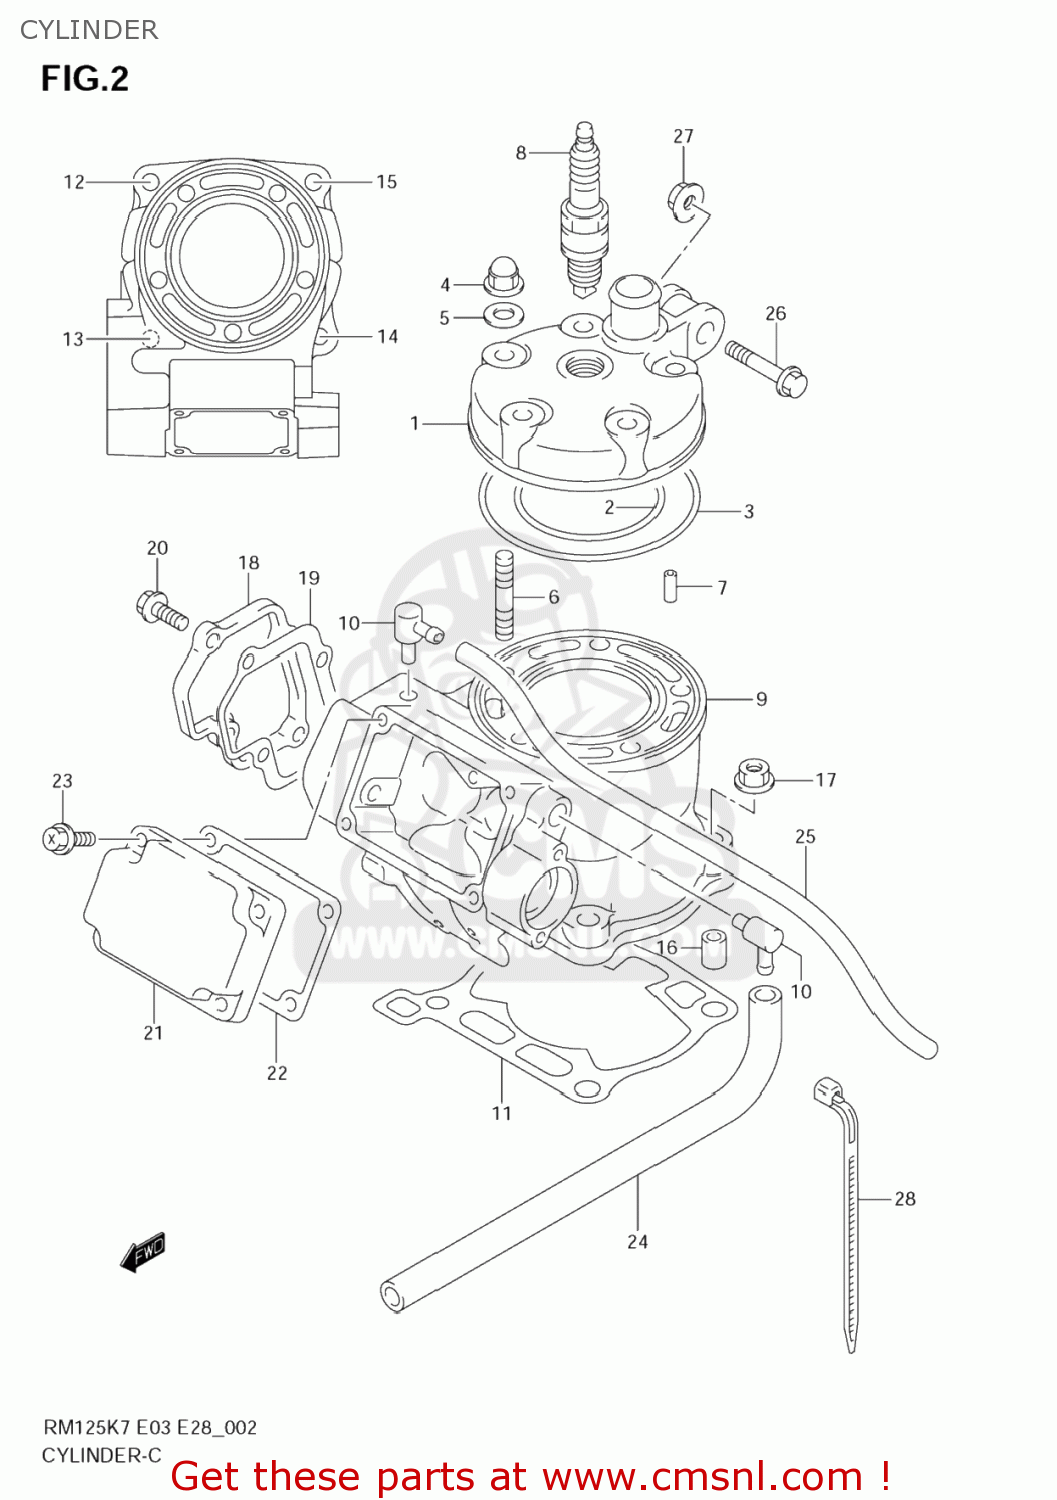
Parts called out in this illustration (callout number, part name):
1	HEAD,CYLINDER
2	O RING,CYLINDER HEAD NO.1
3	O RING,CYLINDER HEAD NO.2
4	NUT
5	GASKET(8.5X17X2.3) (NAS)
6	BOLT,STUD
7	PIN
8	PLUG,SPARK(R6918B-8)
9	CYLINDER SET
10	UNION,BREATHER HOSE
11	GASKET,CYLINDER (NAS)
12	BOLT,STUD
13	BOLT,STUD
14	BOLT,STUD
15	BOLT,STUD
16	PIN(8.4X11X14)
17	NUT
18	COVER,CYLINDER NO.1
19	GASKET,CYL COVER NO.1 (NAS)
20	BOLT(6X16)
21	COVER,CYLINDER NO.2
22	GASKET,CYL COVER NO.2
23	BOLT,CYLINDER
24	HOSE(5X8.2X600)
25	HOSE(5X8.2X600)
26	BOLT(10X47.5)
27	NUT
28	CLAMP(L:165)
